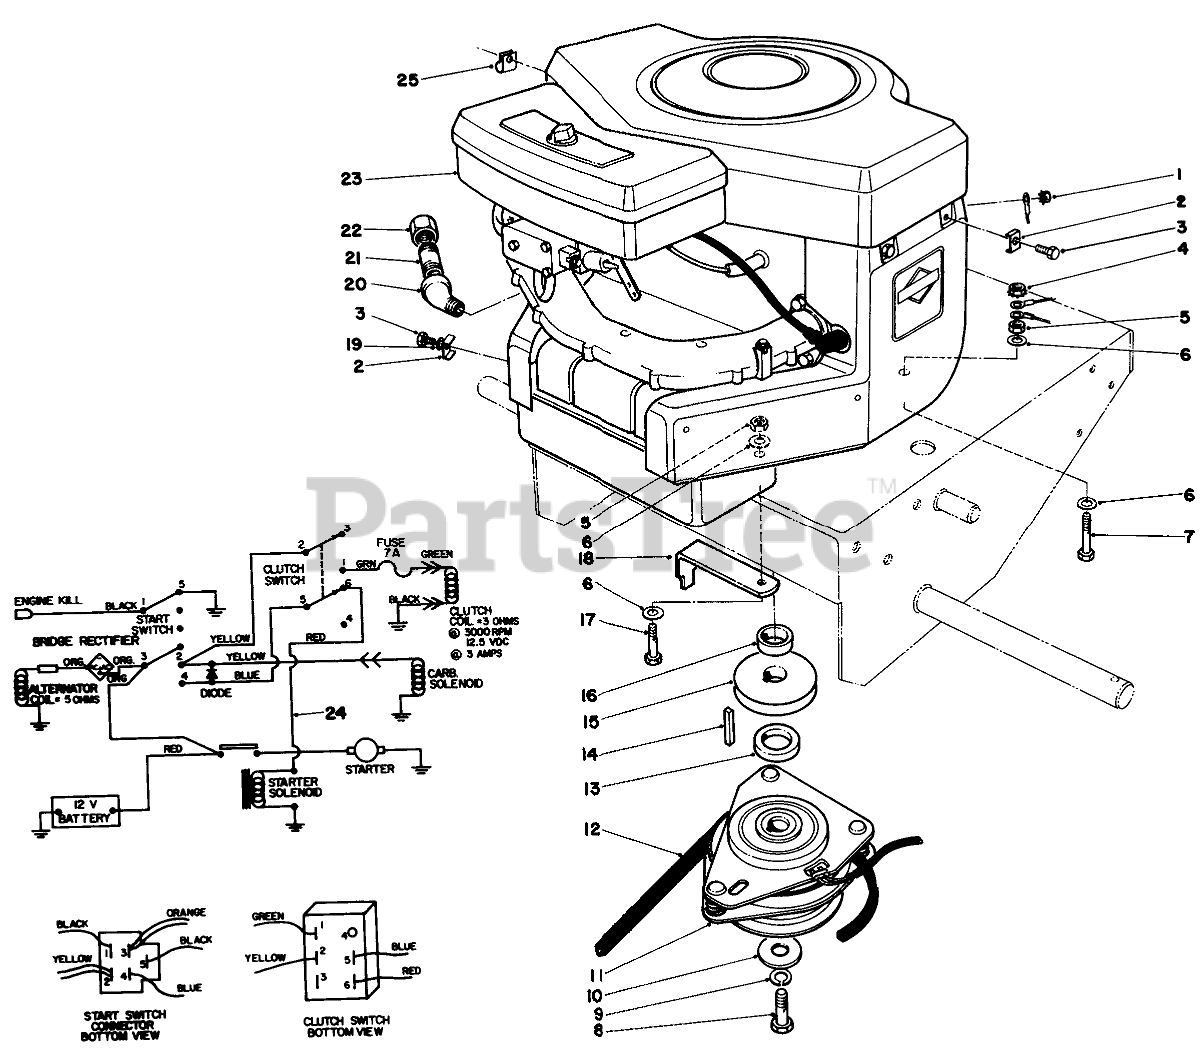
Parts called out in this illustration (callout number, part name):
1	NUT-KEPS
2	CLAMP-CABLE
3	SCREW-HH
4	NUT-KEPS
5	NUT-LOCK, CONE
6	WASHER-PLAIN
7	SCREW-HH
8	SCREW-HH
9	WASHER-LOCK
10	WASHER-CLUTCH
11	CLUTCH/BRAKE
12	V-BELT, DRIVE
13	SPACER-LOWER
14	KEY-SQUARE
15	Pulley-Drive
16	Spacer-Upper
17	SCREW-HH
18	Retainer-Clutch
19	WASHER-LOCK
20	ELBOW
21	NIPPLE
22	CAP-PIPE
23	Engine
24	16 HP WIRE HARNESS
25	CLAMP-R
